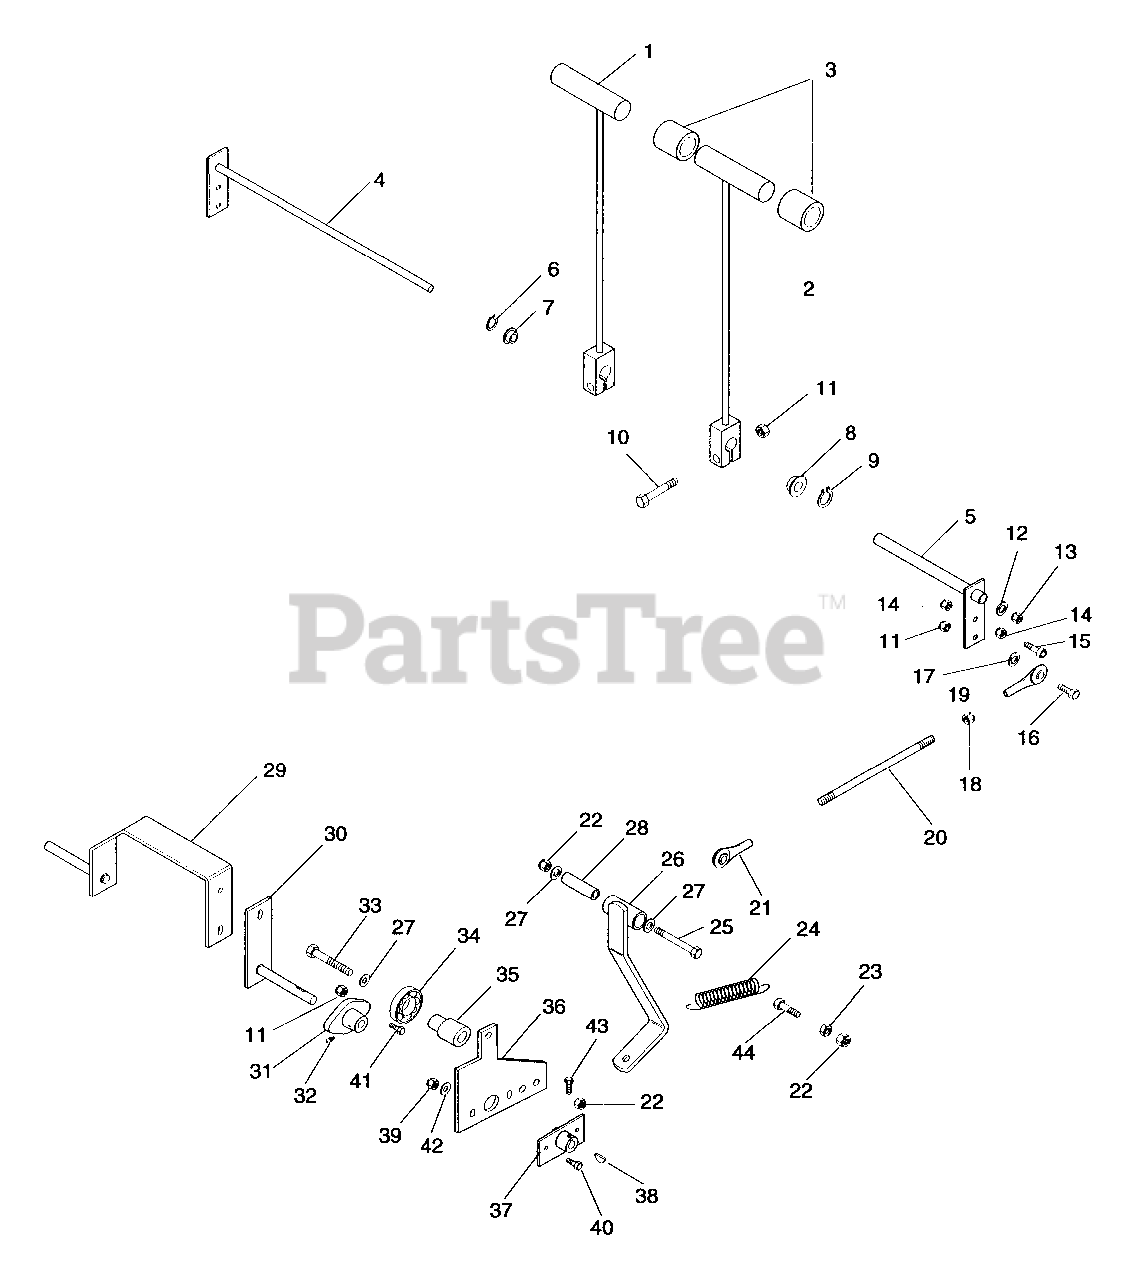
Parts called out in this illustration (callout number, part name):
1	Wldmt, Steering Lever L.H.
2	Wldmt, Steering Lever R.H.
3	Grip, T-Bar
4	Wldmt, Steering L.H.
5	Wldmt, Steering Tube R.H.
6	Rg, Retaining
7	Bush, F .515 x 1.00 x .745 Ny
8	Bshg-Flg .762 x 1.0 x .580 x 1.48 Ny
9	Rg-Rtng-Ext .689 x .077
10	Blt-Hex .31 - 18 x 1.50 Pl Gr 5
11	Nut-Lk-Nyl .312 - 18 Pl
12	Wshr-Fl-Stl .531 x 1.062 x .095
13	Nut-Lk-Nyl .50 - 13 Pl
14	Nut Hex .312 - 18
15	Scr-Set .32-18 x 1.50 Skhcup
16	Blt - Hex .31 - 18 x 1.25 Pl Gr 2
17	Wshr-Fl-Stl .344 x .688 x .065 Pl
18	Nut .312-18 Pl
19	Rod End, 5/16" Female
20	Rod, Steering Adj
21	Rod End, 5/16 - 24 LH Female
22	Nut-Lk-Nyl .375-16 Pl
23	Nut-Hex .375 - 16
24	Sprg, Ext Le - 063F-5
25	Blt-Hex.38-16 x 2.75 Pl Gr 5
26	Wldmt, Neutral Detent
27	Wshr-Fl-Stl .406 x .812 x .065 Pl
28	Bush., S .385 x .610 x 1.80 ST
29	Wldmt, Pump Control R.H.
30	Wldmt, Pump Control L.H.
31	Bush., Flanged Support
32	Ftg, Lube, 25 - 28 Self-Thread
33	Blt-Hex .38 - 16 x 2.00 Pl Gr 5
34	Brg-Ball .500 x 1.375 x .437
35	Hub, Brg. Mount
36	Arm-Speed Control
37	Wldmt, Neutral Adj
38	Key, Woodruff 1/8 x 3/4
39	Nut-Lk-Nyl .250 - 20 Pl
40	Blt-Hex .25 - 20 x .75 Pl Grs
41	Blt-Hex .31-18 x 1.00 Pl Gr 5
42	Wshr-Fl-Stl .281 x .62 x .065 Pl
43	Bolt Hex 1/4 - 20 x .50
44	Blt-Hex .38 - 16 x 1.125
